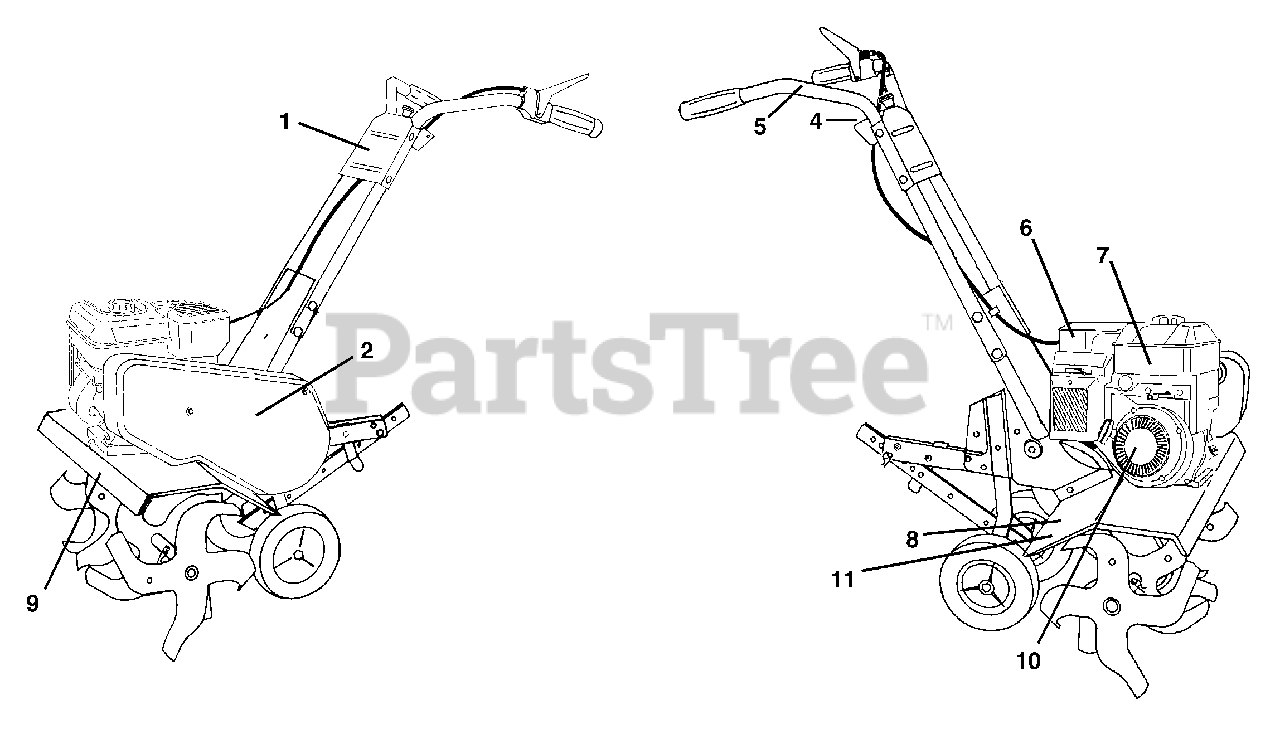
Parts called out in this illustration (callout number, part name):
1	Decal, Logo (Statesman)
1	Decal, Logo (Agway)
2	Decal, Logo (Statesman)
2	Decal, Logo (Agway)
4	Decal, Reverse, Tine Control
5	Decal, Hand Placement
6	Decal, Eng. Tiller
7	Decal, OHV. N-I/C
8	Decal, Warning, Rotating Tines
9	Decal, Hvy Duty
10	Decal, Rewind Intek
11	Decal, Tine Shield Wrng. Dom
